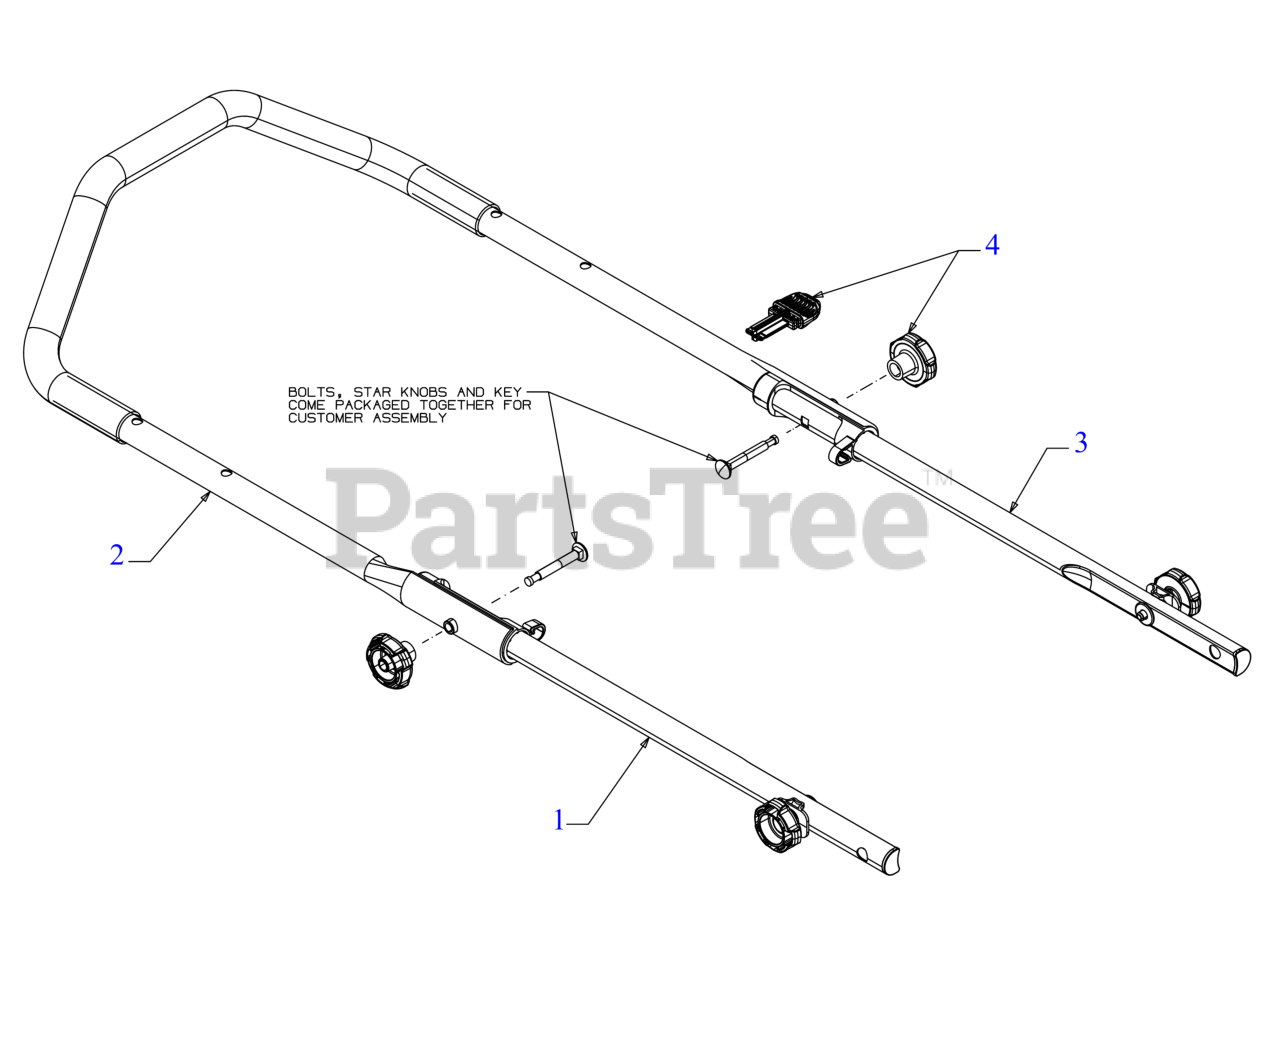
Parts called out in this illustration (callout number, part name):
1	HANDLE (LOWER)
2	HANDLE (UPPER)
3	HANDLE (LOWER)
4	HARDWARE KIT (KNOB/KEY) (YELLOW)
